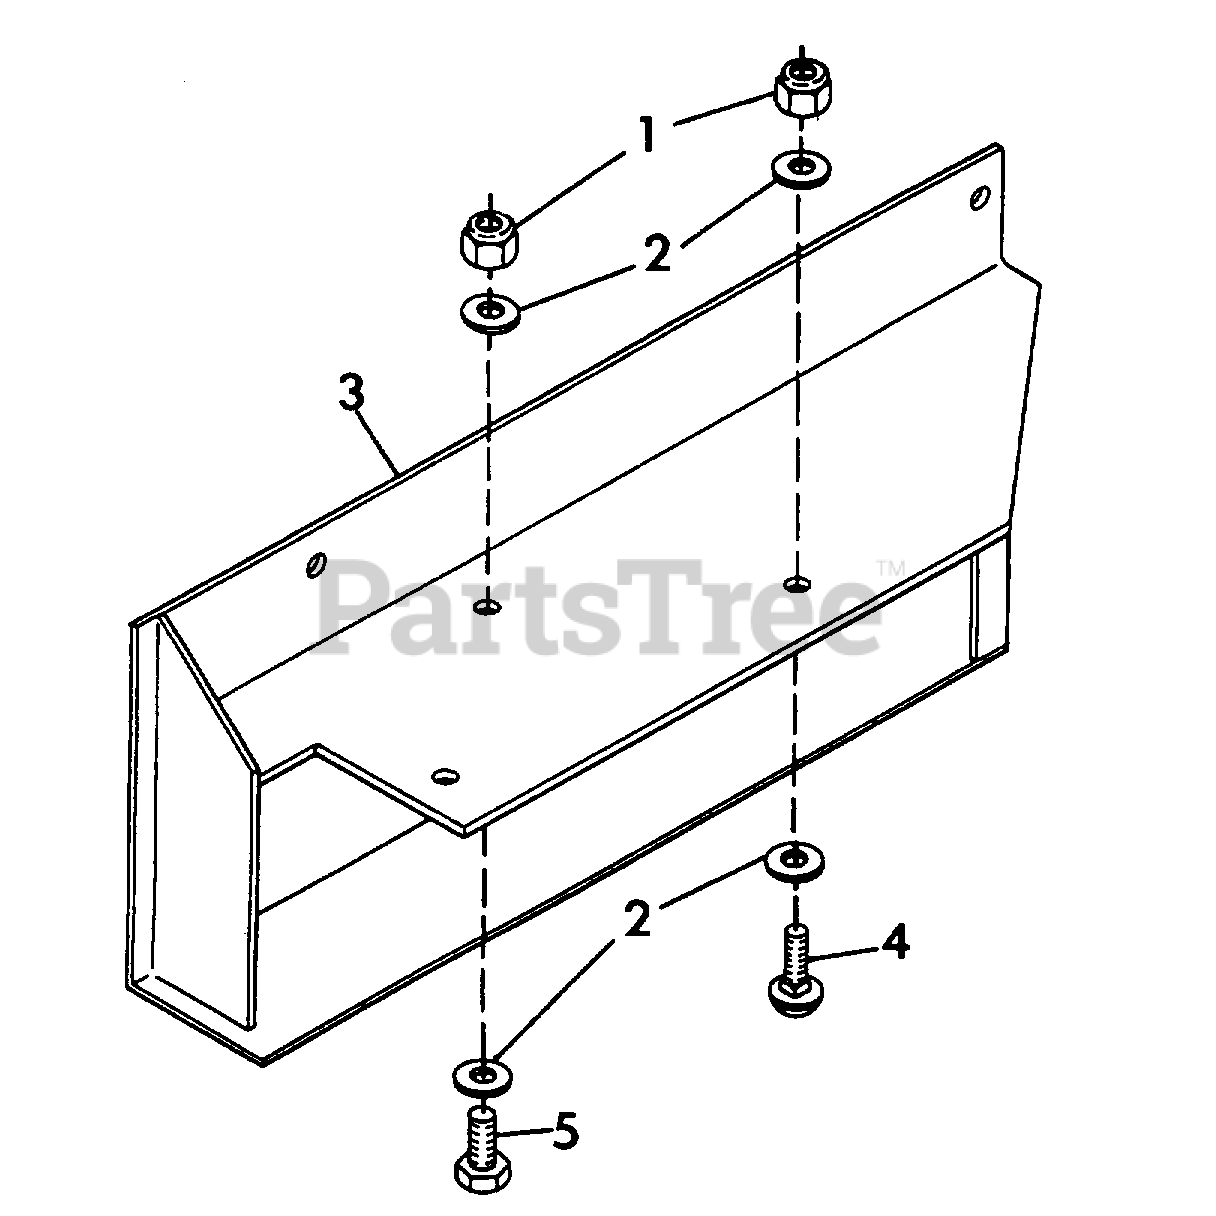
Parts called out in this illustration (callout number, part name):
1	NUT, LOCK 3/8-16
2	WASHER, FLAT .406X.812X.065
3	WELDMENT, CHUTE ADAPTER
4	BOLT, 3/8-16X1.00 RD HD SQ NK
5	BOLT, HEX 3/8-16X1.00
